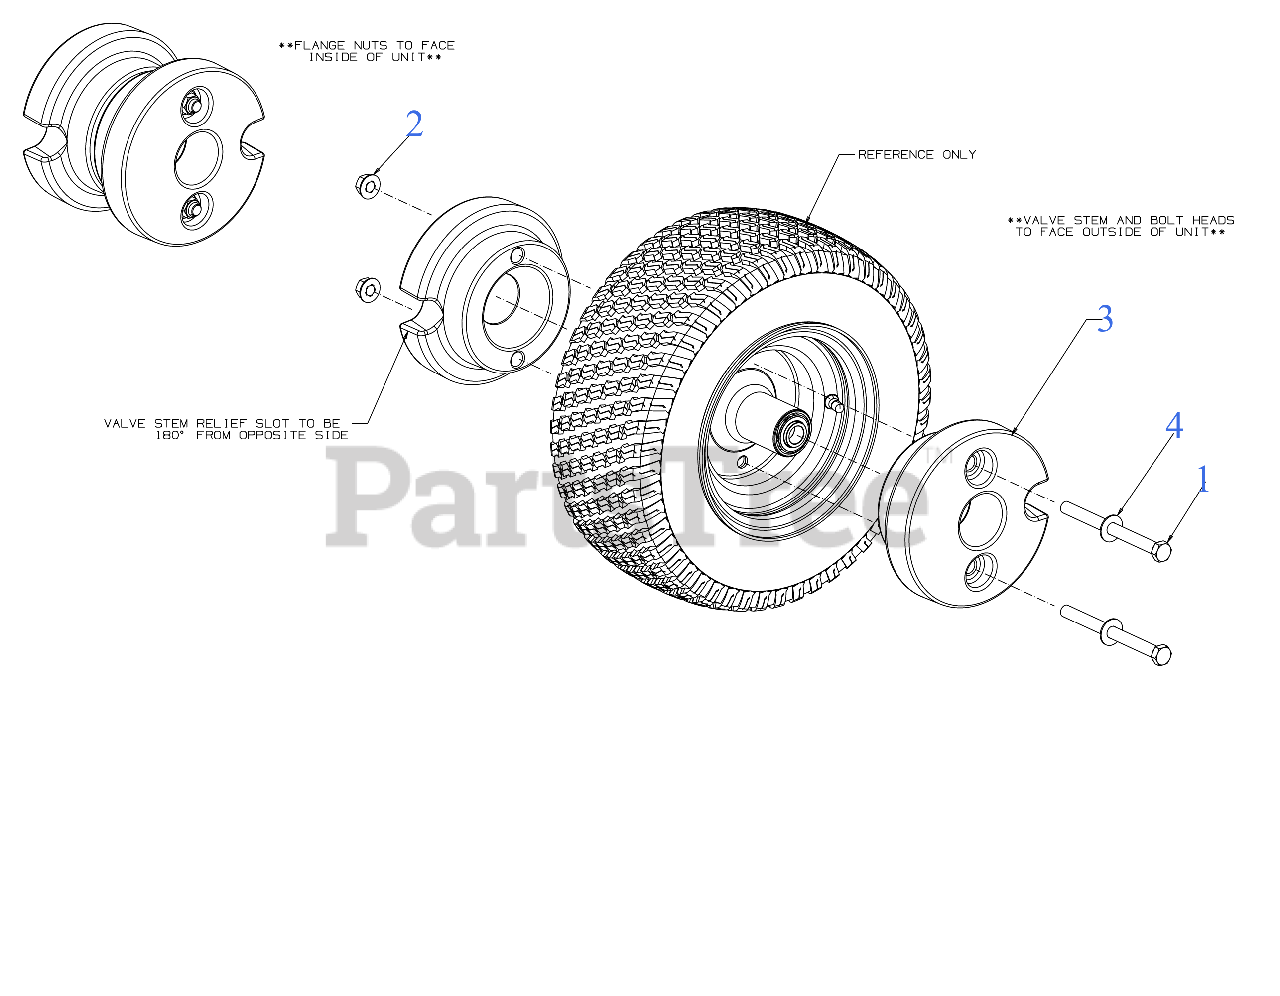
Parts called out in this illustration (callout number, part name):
1	SCREW 1/2-13 x 6.0 GR5
3	WHEEL WEIGHT
4	FLAT WASHER
